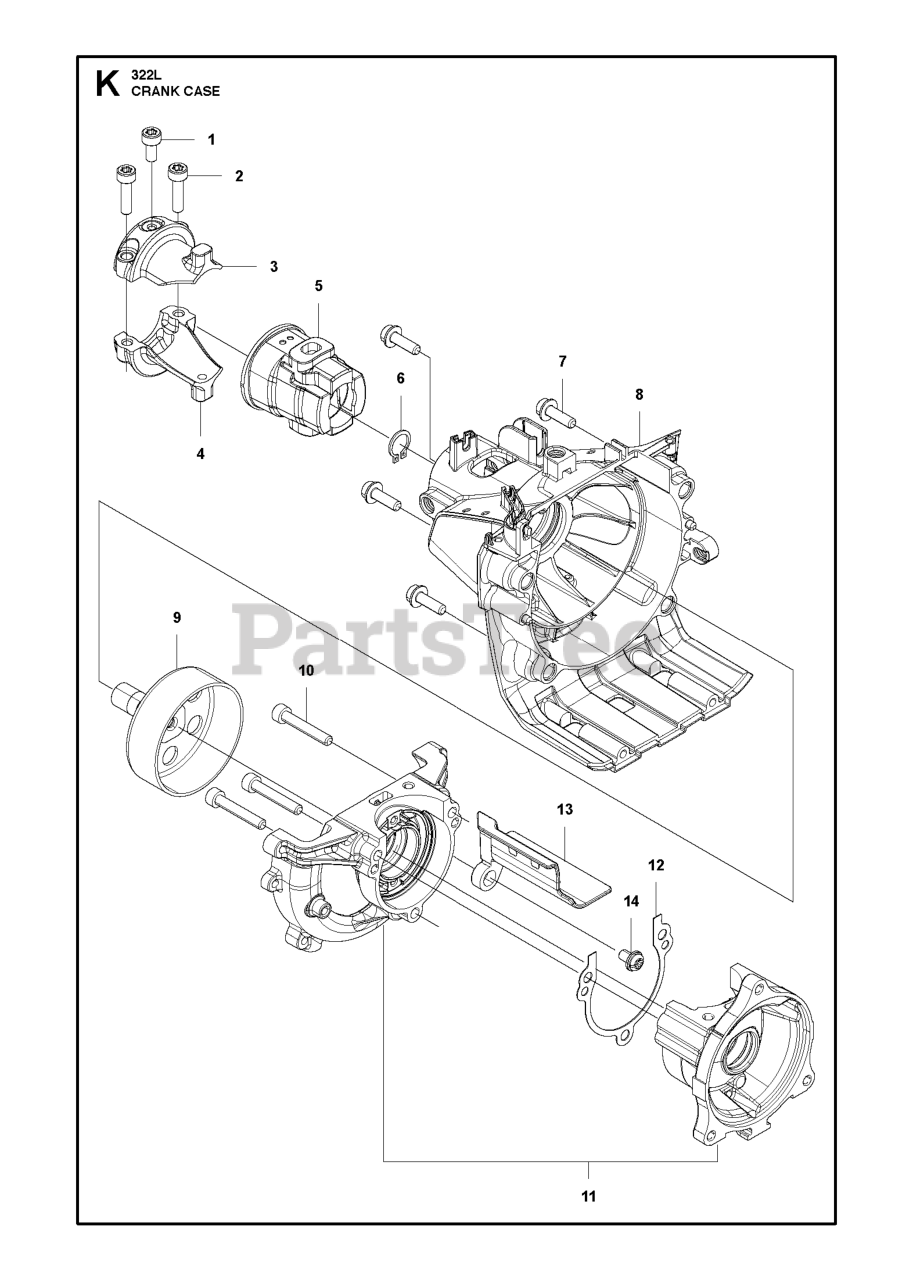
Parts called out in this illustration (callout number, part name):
2	BOLT M5X20 T27
3	BRACKET UPPER M5X0.8
4	BRACKET LOWER
5	CUSHION UPPER
7	BOLT M5 X 16
8	HOUSING CLUTCH
9	CLUTCH DRUM
11	CRANKCASE ASSY
12	GASKET CASE
